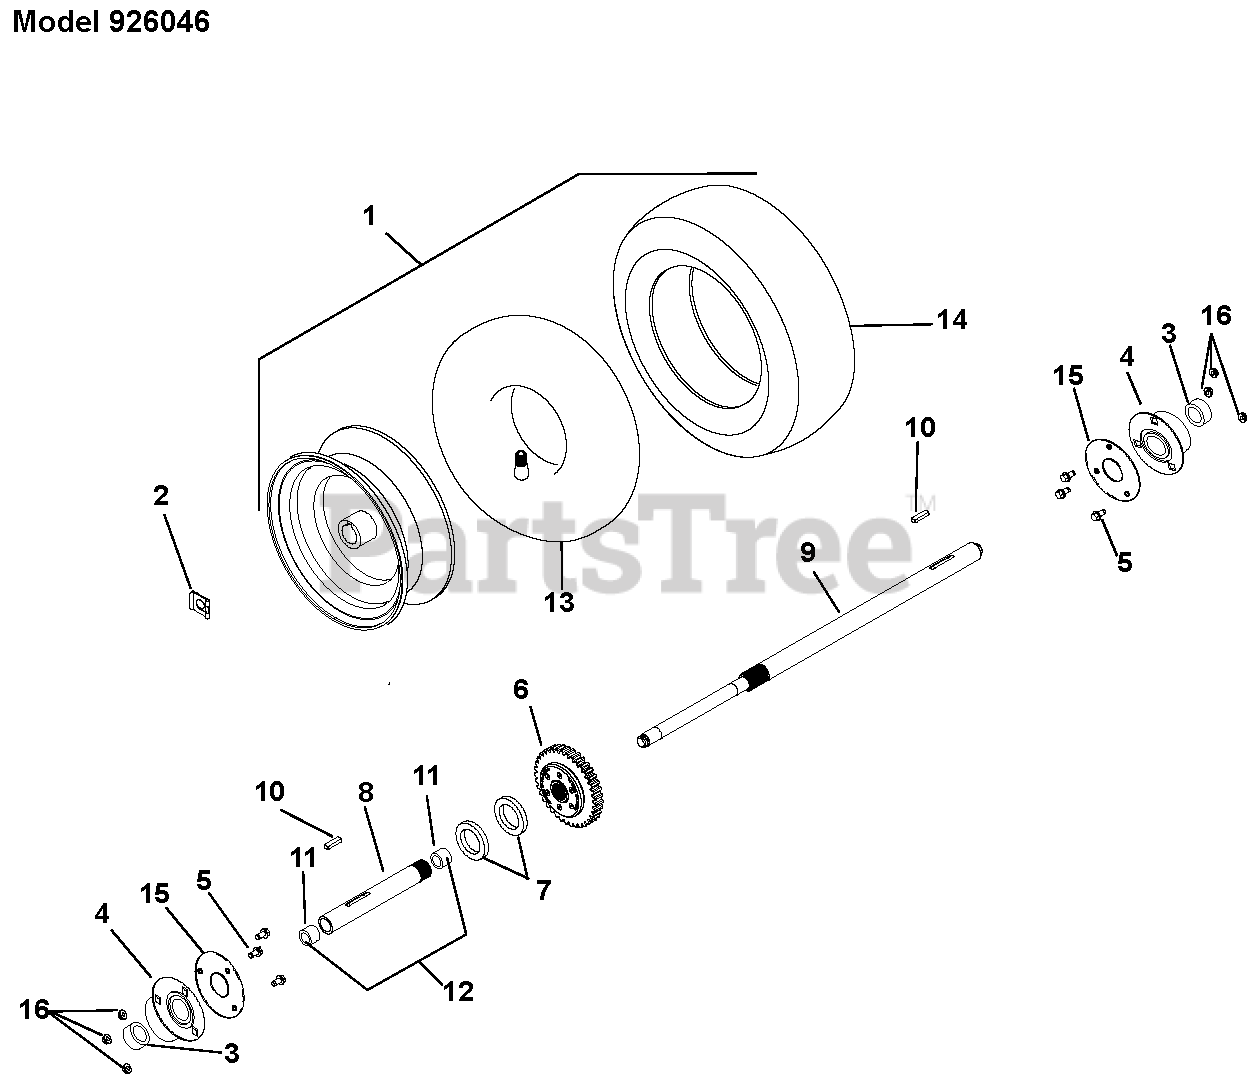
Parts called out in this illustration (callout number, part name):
1	Tire/Wheel Assembly RH 16 x 6.50-8 (Includes Item 14)
2	Clip, Snap
4	Bearing
5	Bolt, Hex .25-20 x .75
6	Differential Assembly
7	Washer, Flat Steel 1.062 x 2.00 x .134
8	Axle, Short (Included in Item 12)
9	Axle, Long
10	Key, Rectangular .25 x .188 x 1.00
11	Bushing, Sleeve (Included in item 12)
12	Axle, Short with Bushings (Includes Items 8 and 11)
13	Tube 16 x 6.50-8
14	Tire 16 x 6.50-8 K478
15	Plate, Bearing Spacer
16	Nut, Locking Top Flange .25-20
